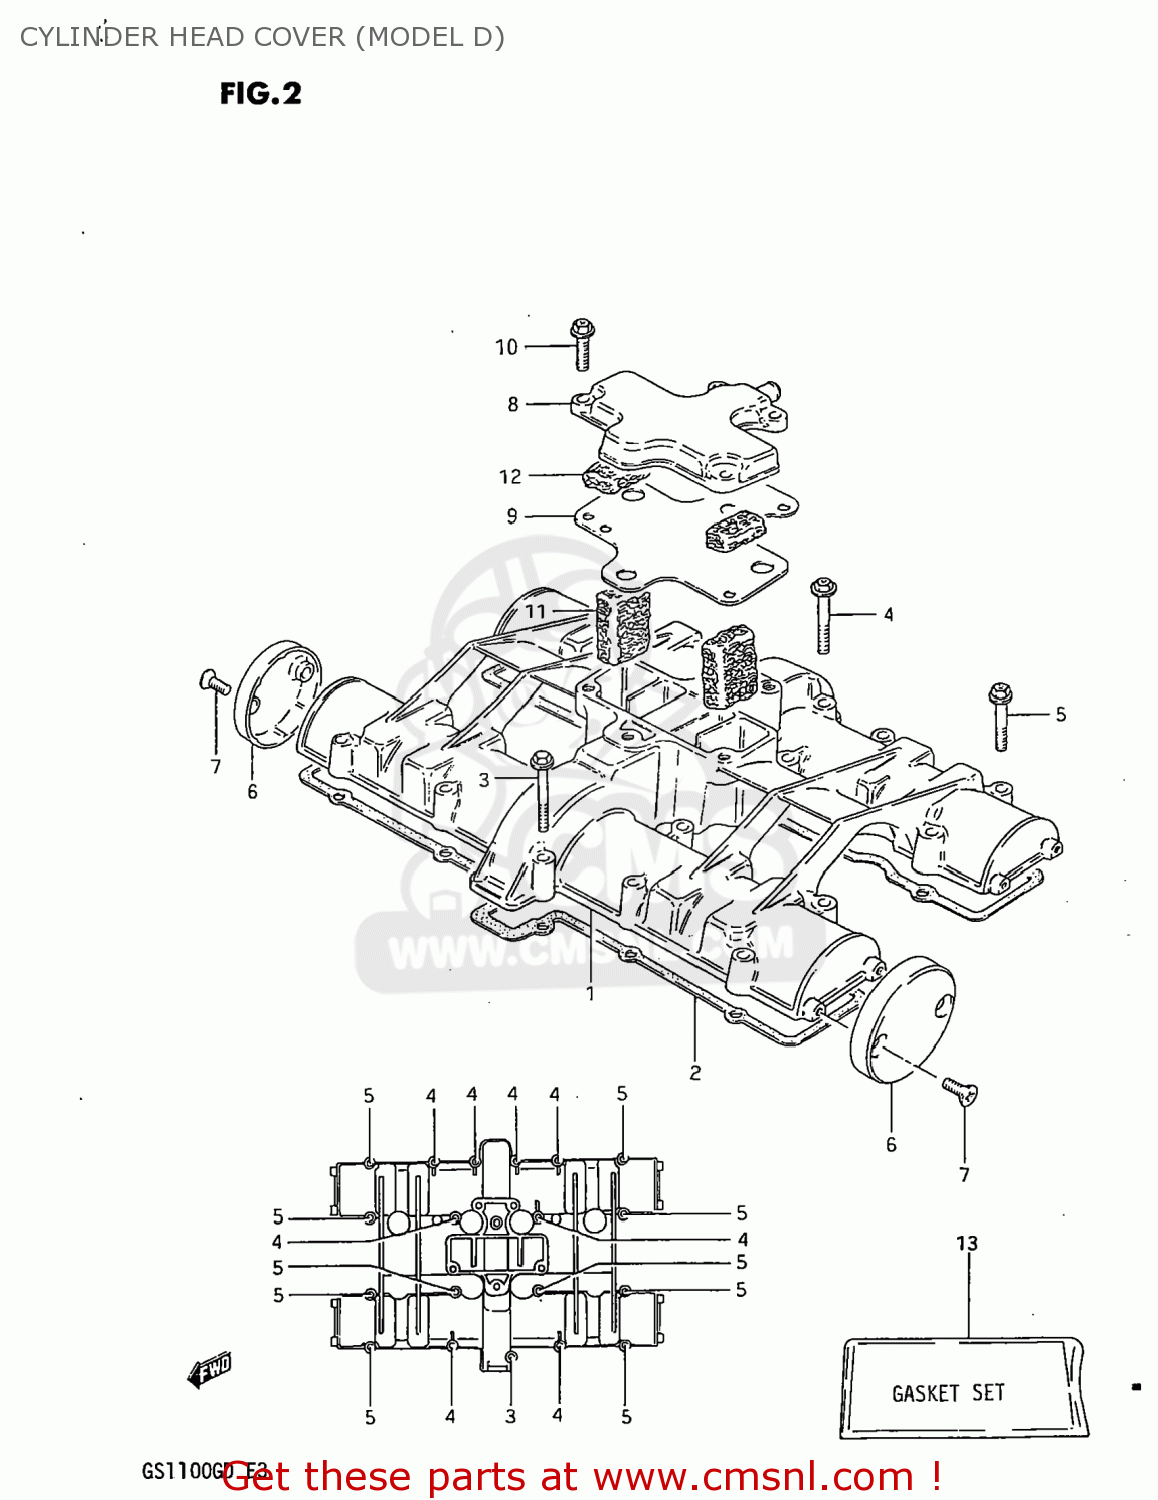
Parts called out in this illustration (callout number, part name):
1	COVER,CYLINDER HEAD
2	GASKET,CYLINDER HEAD COVER (MCA)
3	BOLT (6X45)
4	BOLT (6X40)
5	BOLT
6	CAP,CYLINDER HEAD COVER
7	SCREW(5X12)
8	COVER,BREATHER
9	GASKET (MCA)
10	BOLT
11	COVER,BREATHER
12	SEPARATOR,OIL BREATHER
13	GASKET SET
